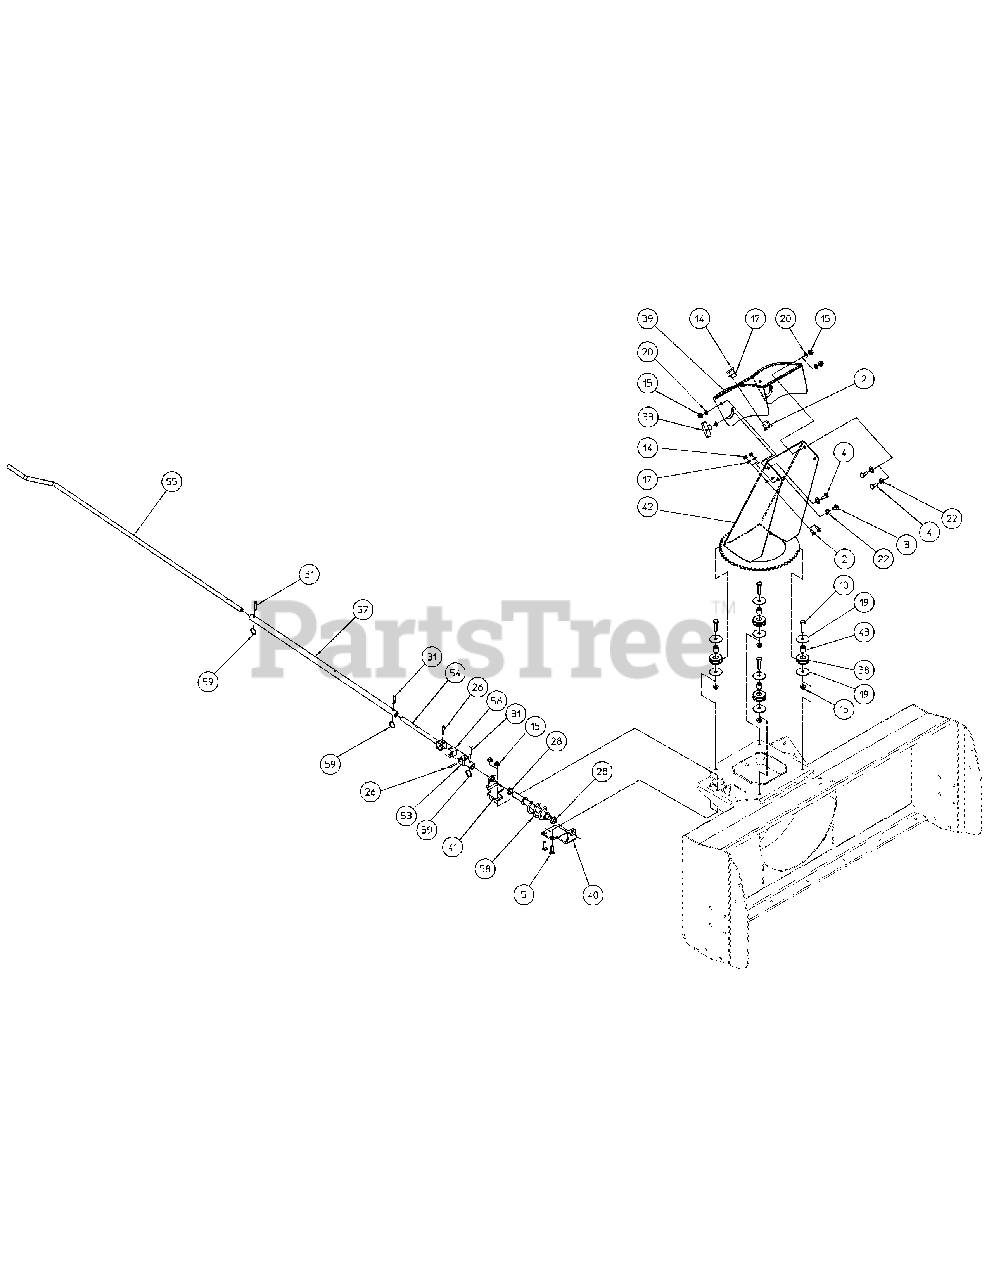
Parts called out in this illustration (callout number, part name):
2	CARRIAGE BOLT 5/16-18X.75 G5 SAE ZY
3	CARRIAGE BOLT 3/8-16X.75 ZY
4	CARRIAGE BOLT 3/8-16X1.0 ZY
5	CARRIAGE BOLT 3/8-16X1.25 G5 SAE ZY
10	HEX HEAD CAP SCREW 3/8-16X1.75 G8 ZY
14	NUT HEX 5/16-18 G5 ZY LOCK
15	NUT HEX FLG 3/8-16 GF ZY LOCK-NYL
17	FLAT WASHER 5/16 ZY SAE
19	FLAT WASHER 3/8 .39X2.0X.125 ZC
20	FLAT WASHER 3/8 NYL BLK
22	FLAT WASHER 1/2 NYL WHT
28	BUSHING-NYLON SHOULDER
31	PIN-CLEVIS (1/4 X 1-1/2)
33	KNOB-PLASTIC BAR
38	BUSHING-CHUTE
39	WELDMENT-CHUTE DEFLECTOR
40	PLATE-LOWER PINION SUPPORT
41	PLATE-UPPER PINION SUPPORT
42	WELDMENT-CHUTE
43	BUSHING-LONG
53	WELDMENT-LOWER YOKE
54	WELDMENT-CHUTE CRANK
55	ROD-CHUTE ROTATION
56	BLOCK-PIVOT JOINT
57	TUBE-SPLICE
58	WELDMENT-CHUTE ROTATION WORM
59	RING-LOCKING
